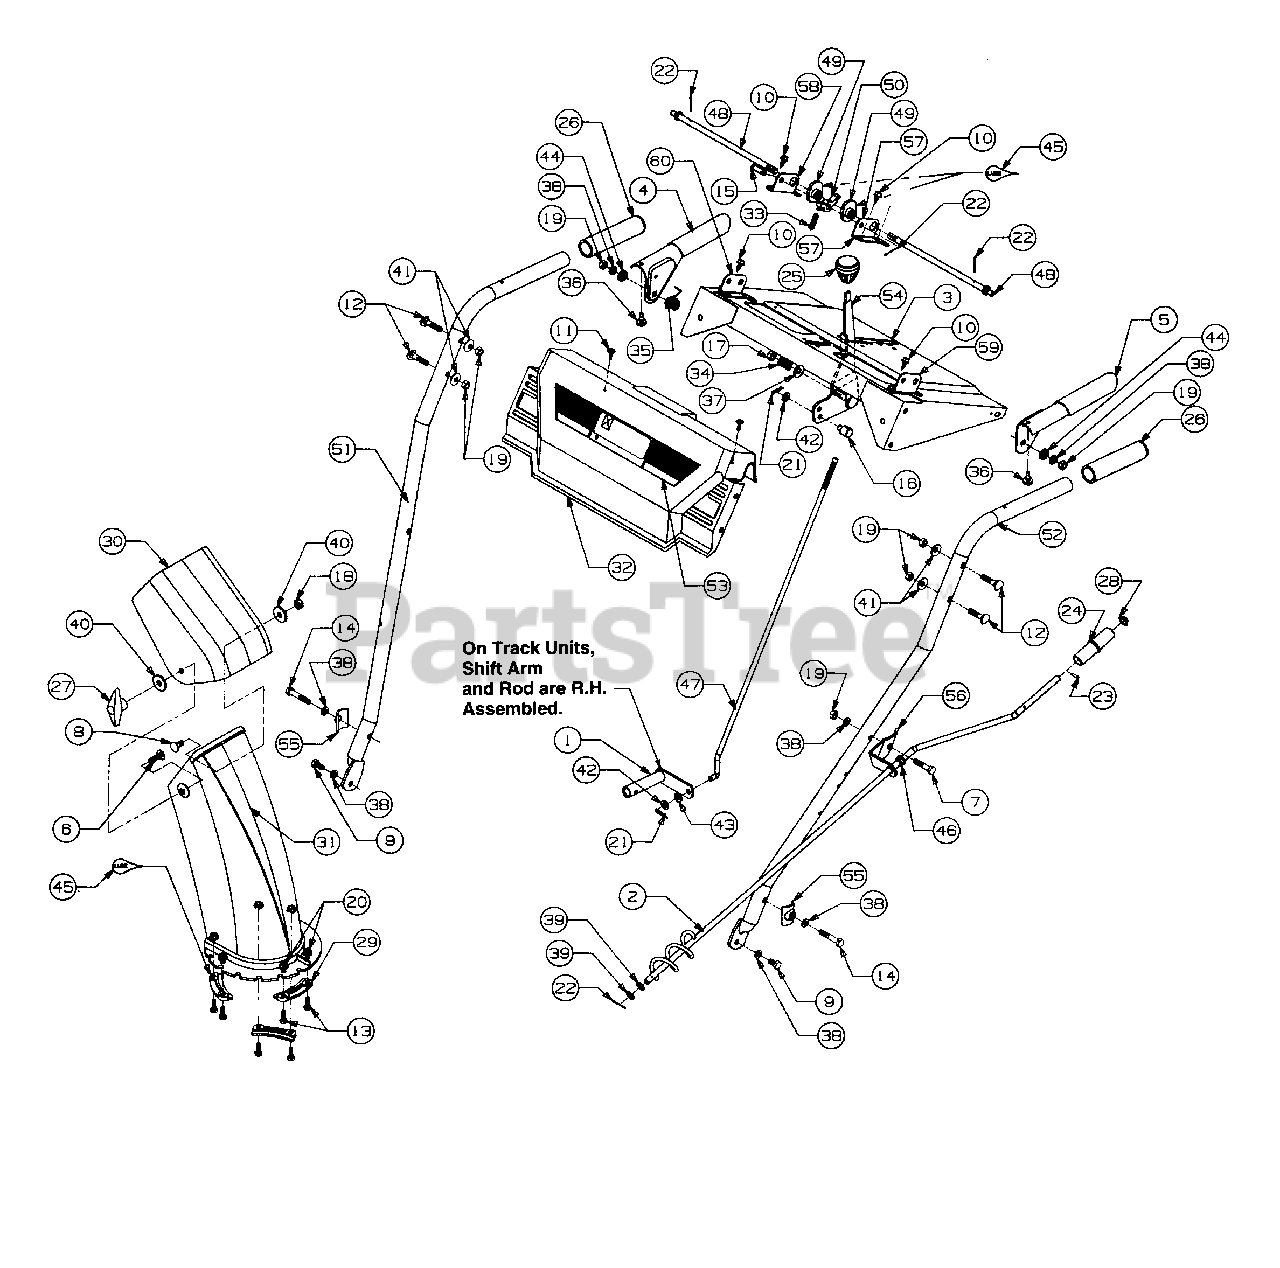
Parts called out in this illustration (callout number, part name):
2	Crank, Chute
5	Handle Engagement L.H.-Blk.
6	Screw Carriage
7	Screw, Hex
8	Bolt, Carriage
9	Screw, Hex
10	Hex Self-Tap Scr.
11	Screw, Hex
12	Bolt, Curved Carriage
13	Hex Cap Screw
14	Hex Screw
15	Pin, Clevis
16	Ferrule, Engagement
17	Hex Lock Nut
18	Nut, Hex
19	Nut, Hex
20	Nut, Lock, Hex, Flanged 1/4-20
21	Pin, Cotter
22	Pin, Cotter
23	Roll Pin
24	Knob, Chute Crank
25	Knob, Shift
27	Knob, L/Wing Nut
28	Cap, Push
29	Chute, Flange Keeper
30	Chute, Upper 5.0 Dia.
31	Lower Chute, 5" Dia. Plastic
32	Panel-Black
33	Spring
34	Spring
35	Spring
36	Bumper
37	Washer, Bell
38	Lock Washer
39	Flat Washer
40	Washer
41	Washer, Bell
42	Washer, Flat
43	Washer, Spring
44	Washer
45	Lubricant
46	Bushing, Plastic
47	Rod, Shift
48	Rod, Cam
49	Cam Handle Lock
50	Pawl Handle Lock
54	Shift Handle
55	Handle Tab
